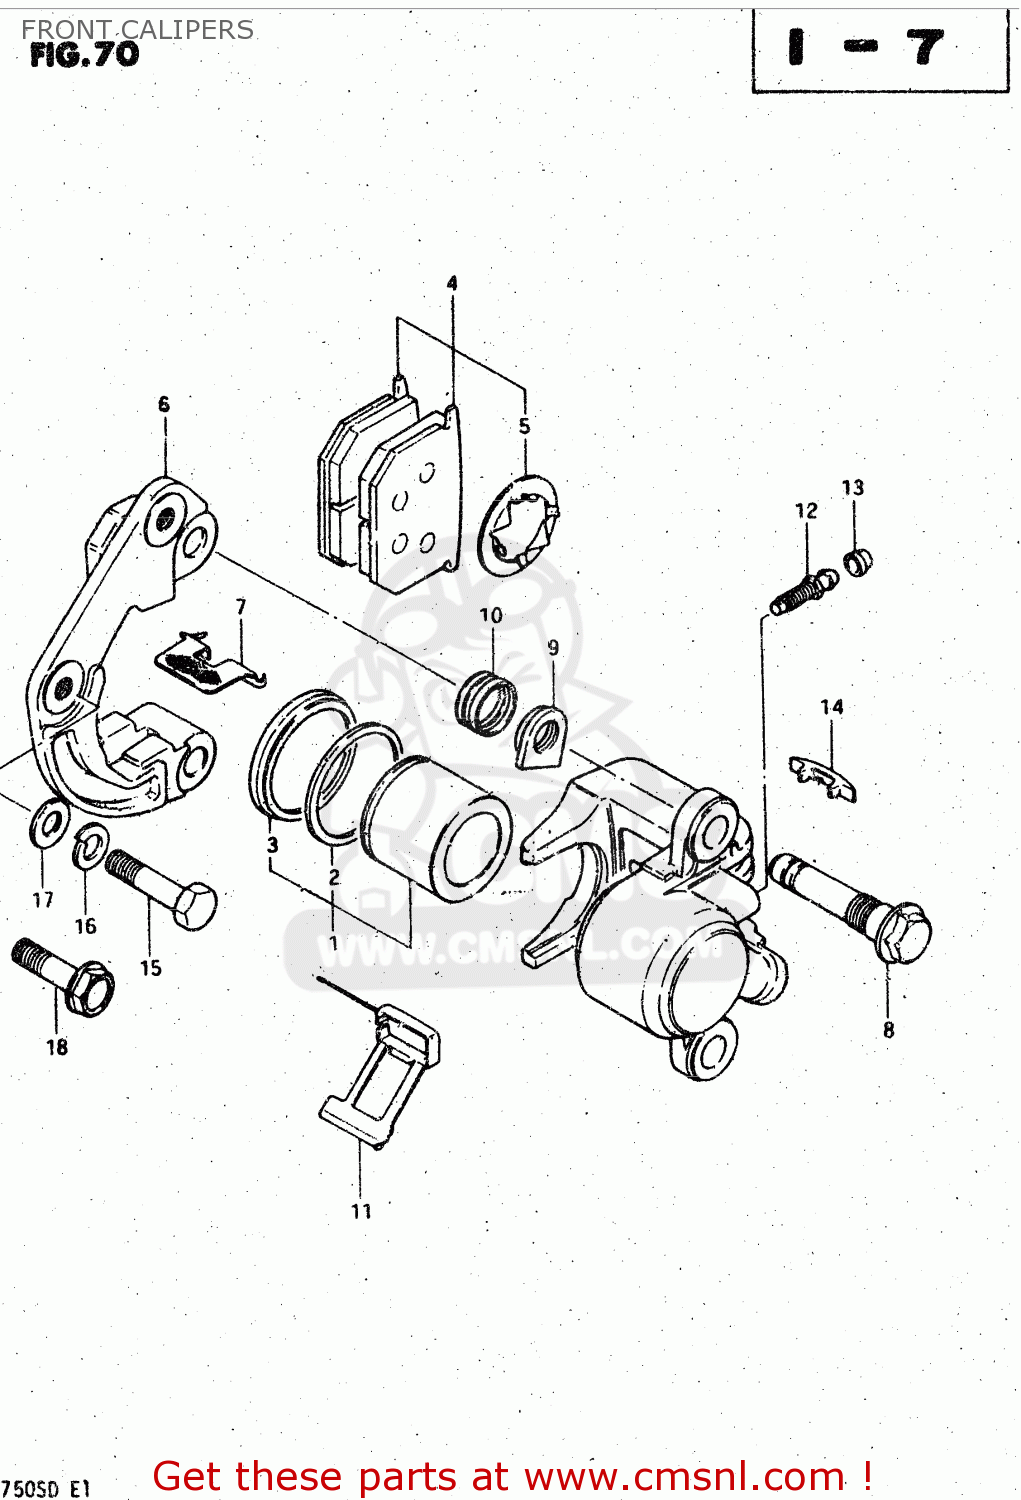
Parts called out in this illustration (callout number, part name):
1	PISTON SET
2	SEAL,PISTON
3	BOOT,PISTON
4	PAD & SHIM SET (MCA)
5	SHIM,PAD
6	HOLDER,CALIPER,LEFT
7	PAD,GUIDE
8	AXLE
9	NUT,CALIPER AXLE
10	BOOT
11	SPRING
12	BREATHER
13	CAP,BLEEDER PL
14	COVER,INDICATOR
15	BOLT
16	LOCK WASHER
17	WASHER
18	BOLT 10X37
